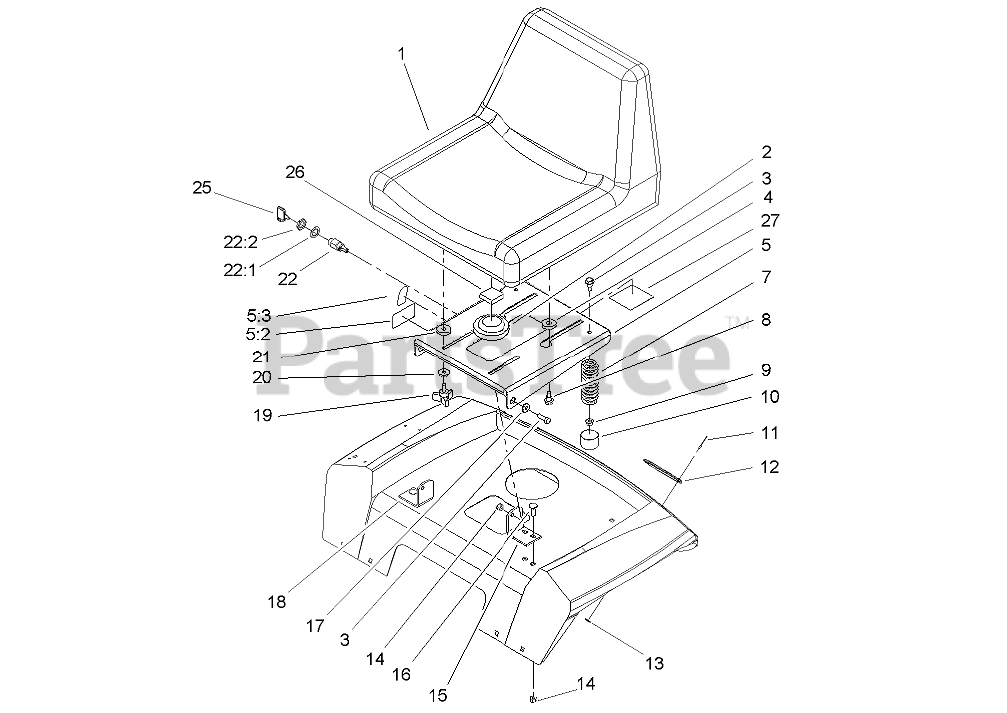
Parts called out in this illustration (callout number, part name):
1	SEAT
2	SWITCH-SEAT
3	SCREW-HH
4	SPACER-NYLON
5	SUPPORT SEAT ASM
5:2	DECAL-DANGER
5:3	DECAL-SWITCH
7	SPRING-COMPRESSION
8	BOLT-SHOULDER
9	NUT-HF
10	CAP-PROTECTOR
11	RIVET-BLIND
12	REFLECTOR-STICK ON
13	WASHER-PLAIN
14	NUT-LOCK, NI
15	BRACKET-PIVOT, RH
16	SCREW-CARR
17	BUSHING
18	BRACKET-PIVOT, LH
20	WASHER
21	SPACER-NYLON
22	STARTER SWITCH ASM
22:1	WASHER-TOOTH, INTERNAL
22:2	NUT-HH
25	KEY-IGNITION
26	FOAM-SWITCH, SEAT
27	DECAL-NOISE
